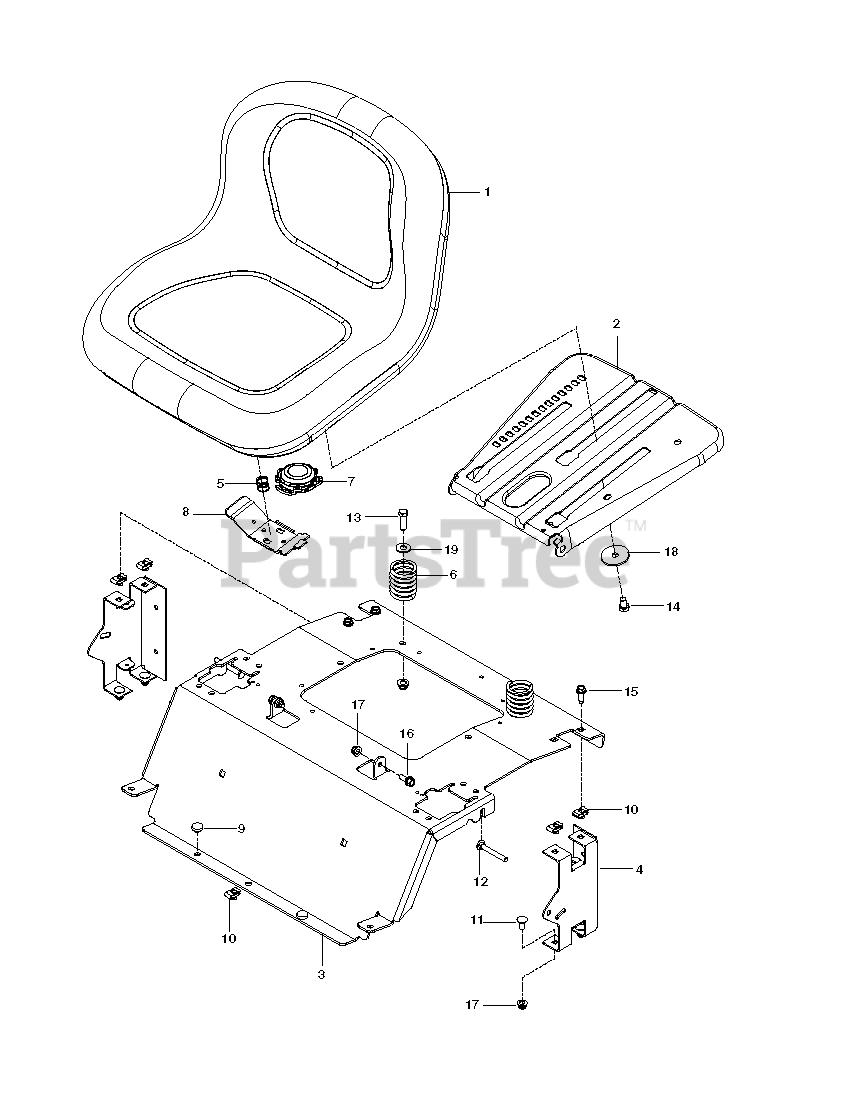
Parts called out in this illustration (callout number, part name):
1	SEAT.TG150.BLK.NLOGO.
2	PAN.ASM.SEAT.3PT
3	SUPPORT SEAT BLUE
4	SUPPORT REAR SEAT BLACK
5	SPRING.LATCH.SEAT.TEX
7	SWITCH, SEAT N/C
8	HANDLE.SLIDE.SEAT.TEX.BLACK
9	GROMMET, BUMPER
10	U-CLIP 5/16-18 NUT RETAINER
11	BOLT 5/16C X 3/4" CARRIAGE
12	RHSNB 5/16-18 X 2-1/2 GR5 ZD
13	HCS 3/8C X 1 1/4 GR5
14	HCS 3/8-16 X 5/8 GR 5 ZD
15	BOLT 5/16-18 X 3/4
16	BOLT, SHOULDER
17	5/16-18 NYLOC FLANGE NUT
18	WASHER, 3/8 SPEC
19	WASHER 3/8 FLAT
